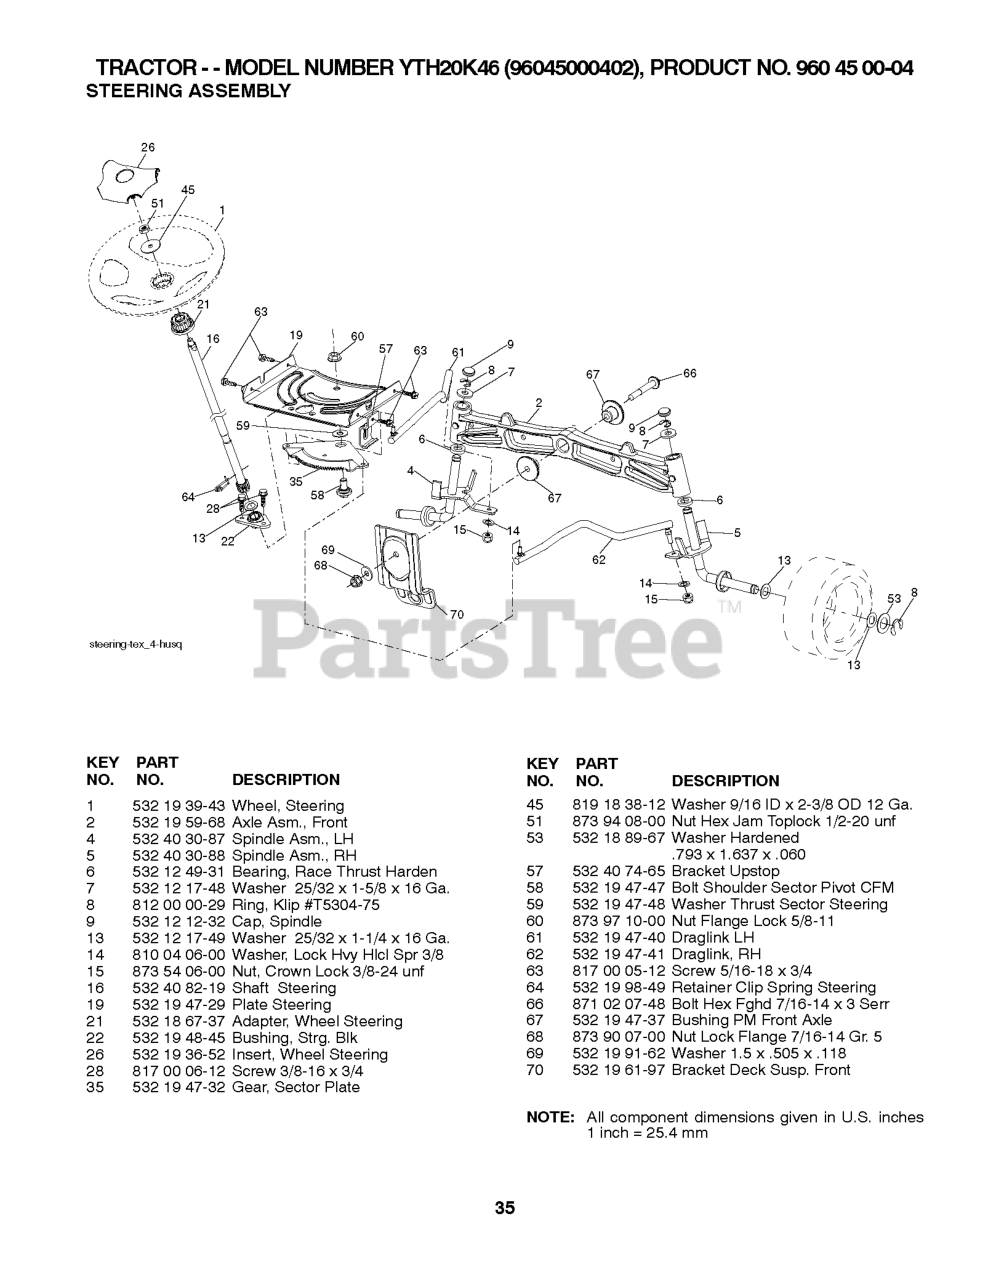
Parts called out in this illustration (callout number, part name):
1	WHEEL.STEERING.LEGEND2.GRY
2	AXLE.CAST.IRON
4	SPINDLE.WELDED.LH.15"TEX
5	SPINDLE.WELDED.RH.15"T
6	THRUST WASHER
9	CAP.SPINDLE.BLACK
14	WASHER, LOCK 3/8
15	NUT CROWNLOCK 3/8-24
16	SHAFT, STEERING
19	PLATE.STEER.DDL.NLT/NG
21	ADAPTER, WHEEL STNG..
22	BUSHING.ASM.STEERING.A
26	INSERT.CAP.STRG.WH.GRAY
28	SCREW, 3/8-16X3/4
35	GEAR.SECTOR.PLATE.DDL.
45	WASHER 9/16"ID, 2 3/8"OD
51	NUT.HEX.1/2-20
53	WASHER.HARDENED
57	BRACKET.UPSTOP.TEX
58	BOLT.SHOULDER.SECTOR.P
59	WASHER.THURST.SECTOR.S
60	NUT FLANGE LOCK 5/8-11
61	DRAGLINK.LH.BALLSTUD.D
62	DRAGLINK.RH.BALLSTUD.D
63	SCREW
64	RETAINER.CLIP.SPRING.S
66	BOLT HEX FGHD 7/16-14 X 3 SERR
67	BUSHING.PM.FRONT AXLE
68	NUT.LOCK.FLANGE.7/16
69	WASHER.1.5X.505X.118
70	BRKT.DECK.SUSPENSION.F
